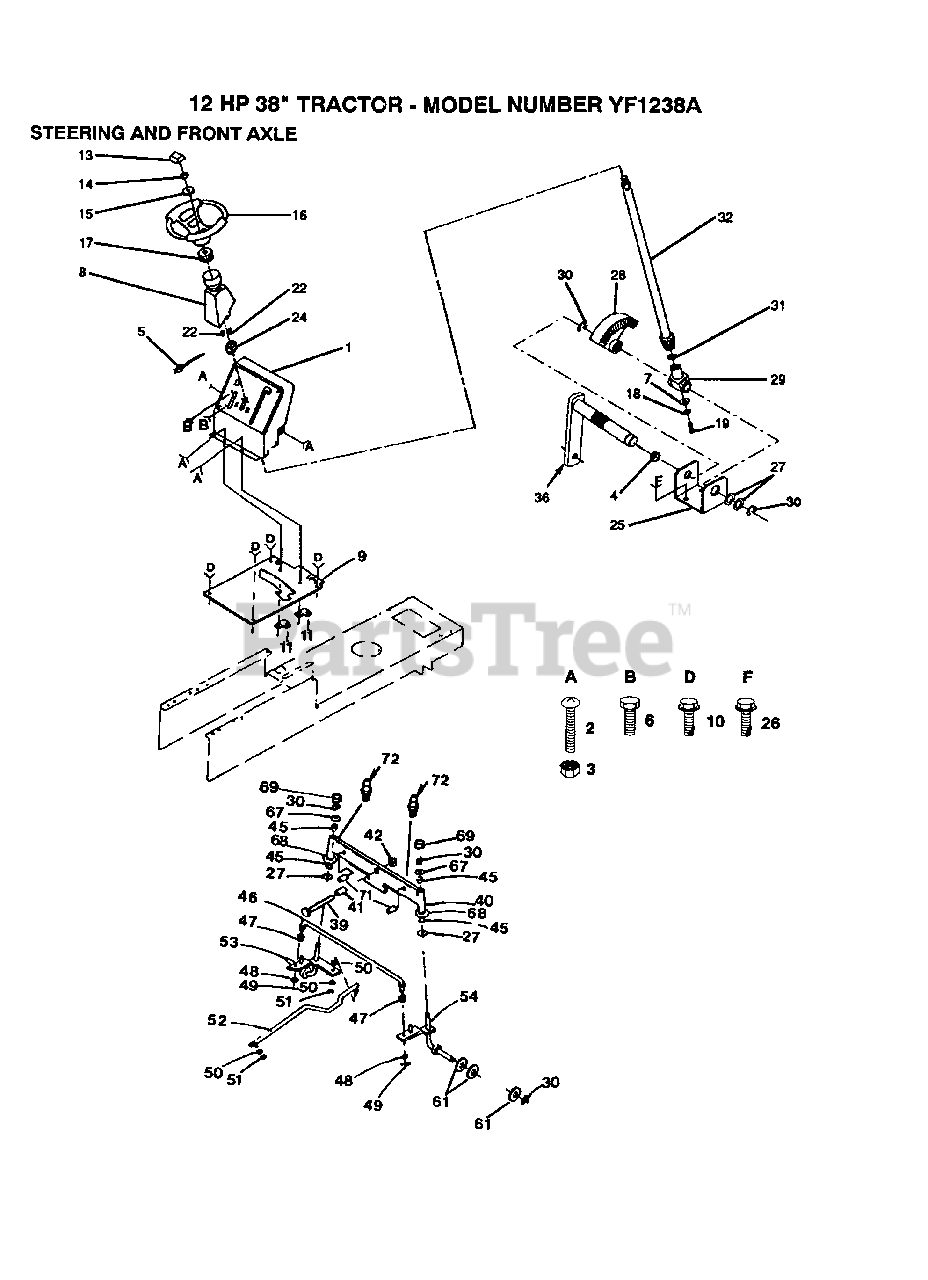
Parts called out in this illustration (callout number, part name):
2	SCREW
4	NYLINER T
5	THROTTLE CONTROL
6	SCREW LT
8	"TUBE, STR SHAFT"
10	SCREW LT
11	CLIP T
13	INSERT STEERING
14	GRIPCO NUT
15	WASHER T
17	ADAPTER-WHEEL LT
18	LOCKWASHER
19	"SCREW,SPECIAL"
25	"BRKT,STEERING"
26	SCREW
27	WASHER .T
29	SUPPORT.SHAFT
30	RING
31	THRUST WASHER
32	SHAFT ASM
39	BOLT HEX 5/8-11
41	BEARING
45	COL. SRTG. BEAR.
46	TIE ROD
47	BUSHING.DRAGLINK
48	WASHER
49	COTTER PIN
50	LOCKWASHER
53	SPINDLE LH
54	SPINDLE RH
61	WASHER
67	WASHER
68	WASHER
69	CAP
71	AXLE PIN
72	ZERK M
